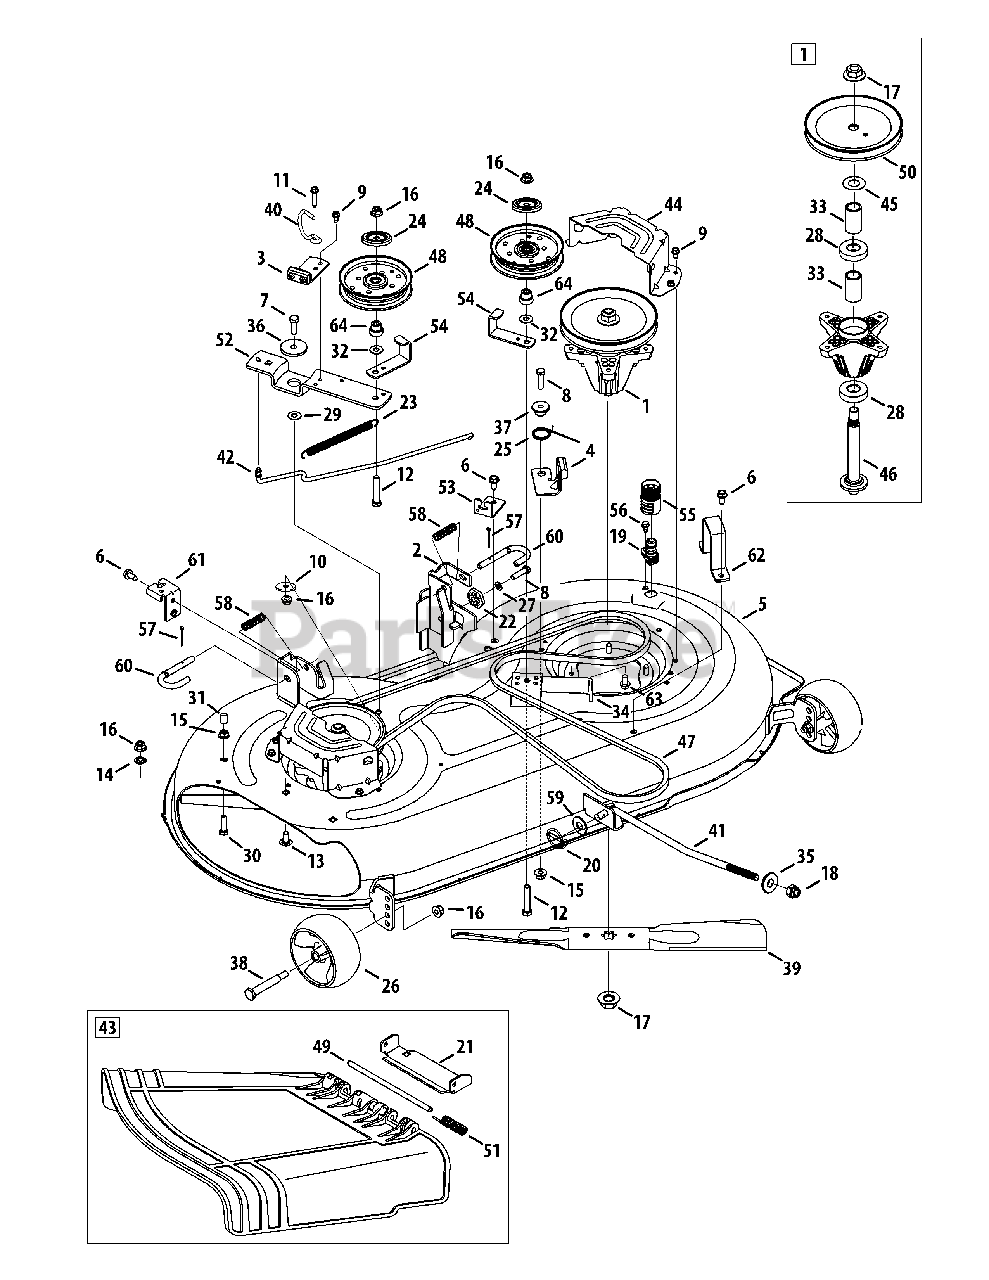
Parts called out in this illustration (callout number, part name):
1	Spindle Ass’y, Pulley, 6.3 Dia
2	Bracket Ass’y, Deck, Hanger LH
3	Brake Ass’y, Deck, 42/46
4	Brake Ass’y, Deck, 46"
5	Deck, Offset, 42" W/O wheel
6	Screw, Self-tapping, 5/16-18, .750
7	Hex Screw, 3/8-16, 1.25, Gr5, Std
8	Hex Screw, 5/16-18, 1.25, Gr5, Std
9	Screw, Self-tapping, 1/4-20, 0.500
10	Flat Washer, .406 x 1.500 x .105
11	Screw, Self-tapping, 1/4-20, .750
12	Hex Screw, 3/8-16, 2.00, Gr5, Std
13	Bolt, Carriage, 3/8-16, 0.75, Gr1
14	Nut, Push, 3/8
15	Nut, Flange Lock, 5/16-18, Grf
16	Nut, Flange Lock, 3/8-16, Grf
17	Nut, Flange, 5/8-18
18	Nut, Lock, 1/2-13
19	Deck Wash Nozzle
20	Lynch Pin, .1875
21	Chute Bracket
22	Gear, Deck, Adjustment
23	Spring, Extension, .62 Dia x 6.12
24	Pulley Cap
25	Spring, Torsion, .992 ID X 1.17 OD
26	Wheel, Deck, 5.0 Dia Ball
27	Washer, Lock, 5/16, Regular Duty
28	Bearing, Ball, .787id x 1.85 Odx.551
29	Washer, Flat, .385 X 1.0 X .030
30	Hex Cap Screw, 5/16-18 x 1.00
31	Cap, .290 x .500
32	Washer, Flat, .385 x .870 x .092
33	Spacer, .792 x 1.060 x 1.860
34	Bracket, Support, Stationary Idler
35	Bell Washer, .63 X 1.25 X .18
36	Spacer, Shoulder, .8840 x .190
37	Shoulder Spacer
38	Bolt, Shoulder, .496 x 2.50, 3/8-16
39	Blade, Cut, 21.23" 2-In-1, Econ
40	Rod, Keepr, Belt 42 Idler
41	Deck Lift Rod
42	Rod, Control, Brake 42"
43	Chut Assembly, 42" Deck
44	Deck Belt Cover, 42
45	Washer, Flat, .760 Idx1.50 OD
46	Shift, Spindle, 6.11.
47	Belt, V Type, A Sec X 96.5
48	Pulley, Idler, 4.25"Dia
49	Pin, Hinge, Dia .3125 x 7.96
50	Pulley, Deck, 6.3 Dia
51	Spring, Torsion, .44 I.D. X 2.0
52	Pivot idler Bracket, 46
53	Bracket, Cable, Deck Engage
54	Bracket, Guard, Belt, 4.25 Pulley
55	Water Nozzle Adapter
56	Shoulder Screw, 1/4-20 x 0.50
57	Cotter Pin, 1/8 X 1.25
58	Comp. Spring, .535 OD X 1.751 LG
59	Flat Washer, .531 X 1.25 X .100
60	Deck Release Handle Rod
61	Deck Engage Cable Bracket
63	Self Tapping Screw, 5/16-18 x .75
64	Shoulder Spacer
